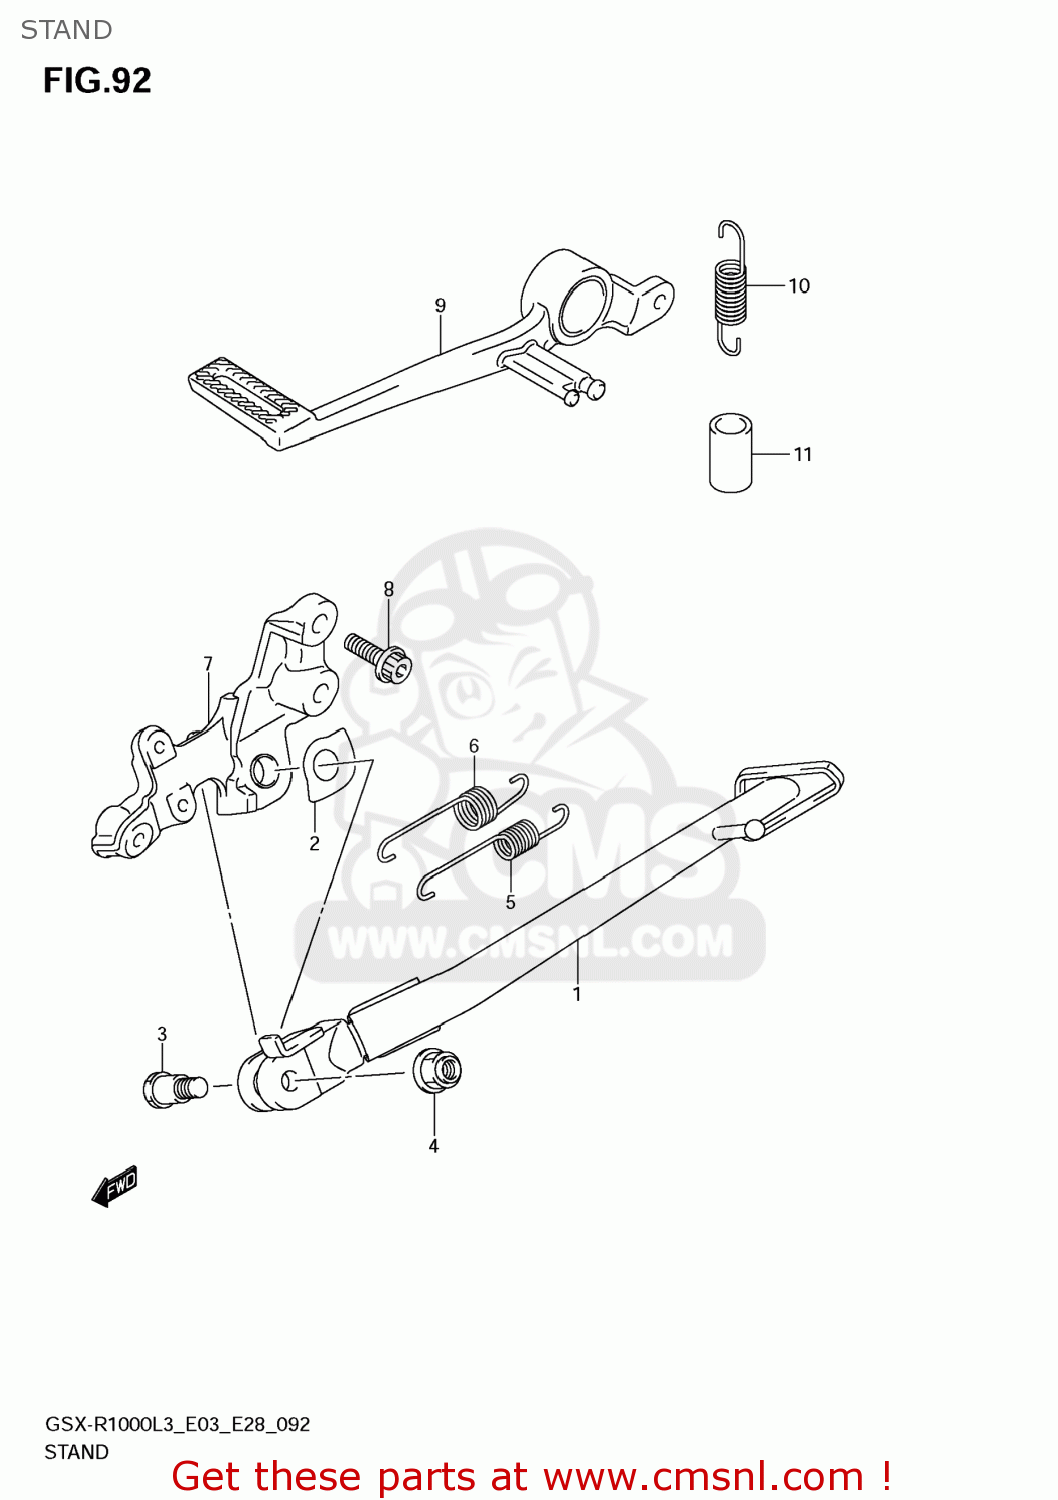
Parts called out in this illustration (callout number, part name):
1	STAND,PROP
2	WASHER,PROP STAND
3	BOLT,PROP STAND
4	NUT
5	SPRING
6	SPRING
7	BRACKET,PROP STAND
8	BOLT(10X28)
9	PEDAL,BRAKE
10	SPRING
11	HOSE(11X15X600)
